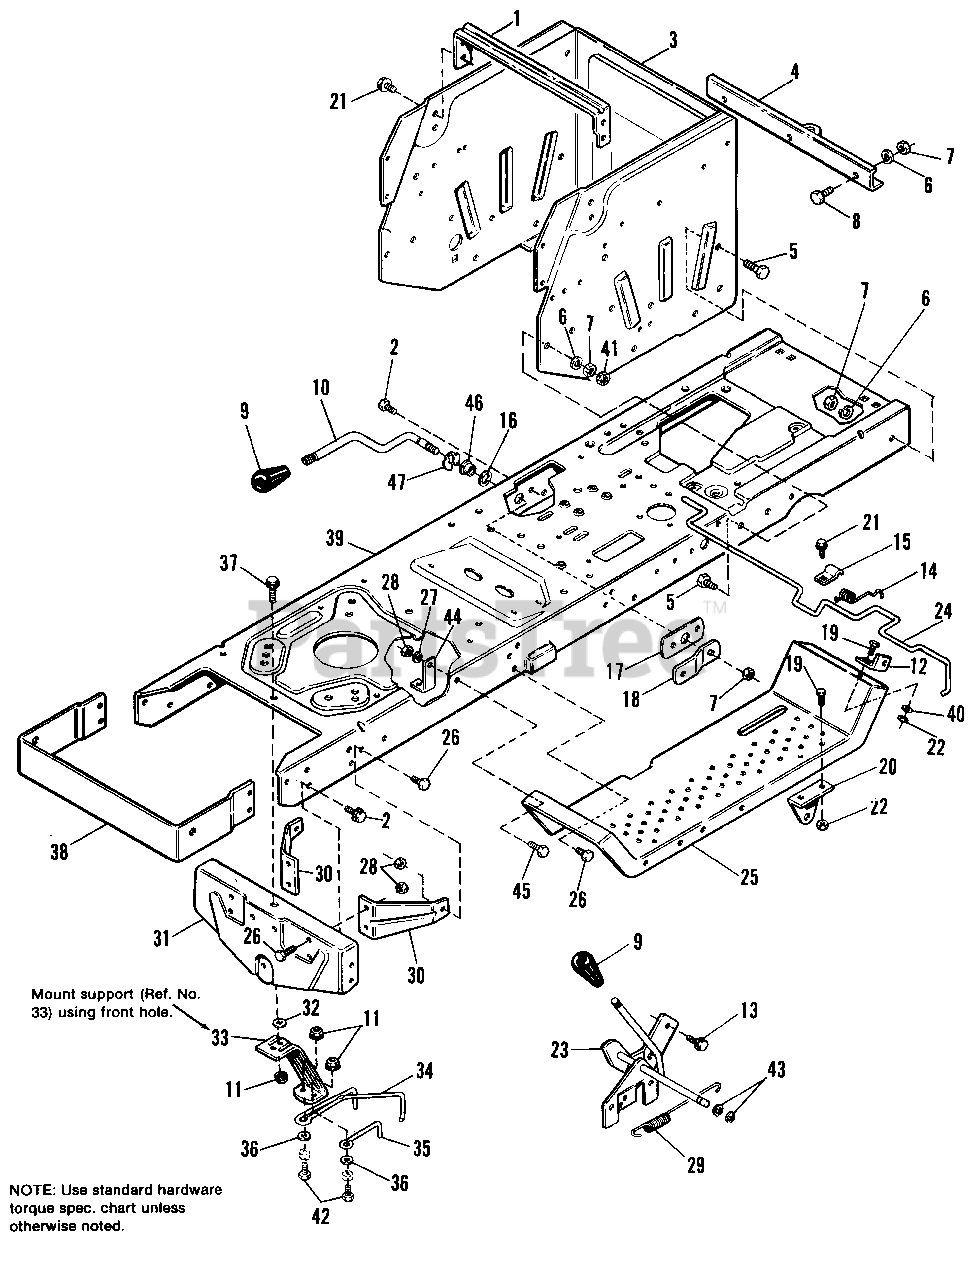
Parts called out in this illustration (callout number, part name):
1	BRACE, Seat
2	SCREW, Taptite, 5/16-18 x 3/4
3	SUPPORT, Axle Wrapper
4	BAR, Draw
5	CAPSCREW, Hex, 3/8-16 x 1, Gr. 5
6	LOCKWASHER, 3/8
7	NUT, Hex, 3/8-16
8	CAPSCREW, Hex, 3/8-16 x 1
9	GRIP, Handle
10	HANDLE, Lift (Incl. Ref. Nos. 46 & 47)
11	NUT, Hex, Flange Whizlock, 5/16
12	BRACKET, Seat Latch
13	SCREW, Taptite, 1/4-20 x 1/2
14	SPRING, Torsion
15	CLIP, Latch Rod
16	WASHER, Nylon
17	BAR, Support
18	ARM, Support
19	CAPSCREW, Hex, 1/4-20 x 5/8
20	SUPPORT, Clutch
21	SCREW, Taptite, 5/16-18 x 1/2
22	NUT, Hex, 1/4-20
23	LEVER ASSY., Clutch
24	ROD, Latch
26	CAPSCREW, Hex, 5/16-18 x 3/4
27	LOCKWASHER, 5/16
28	NUT, Hex, 5/16-18
29	SPRING, Extension
30	BRACE, Axle Support
31	SUPPORT, Axle
32	WASHER, Plain, 11/32-1 x 10 Ga.
36	WASHER, 11/32
37	CAPSCREW, Hex Flange Whizlock, 5/16-18 x 1-1/4
40	WASHER, 9/32 Dia.
41	NUT, Hex, Jam Lock, 3/8-16
42	CAPSCREW, 5/16-18 x 7/8
43	RING, Retaining, 1/2
44	BRACKET, Spring
45	CAPSCREW, Hex, 5/16-18 x 1
47	KLIPRING, 1/2
